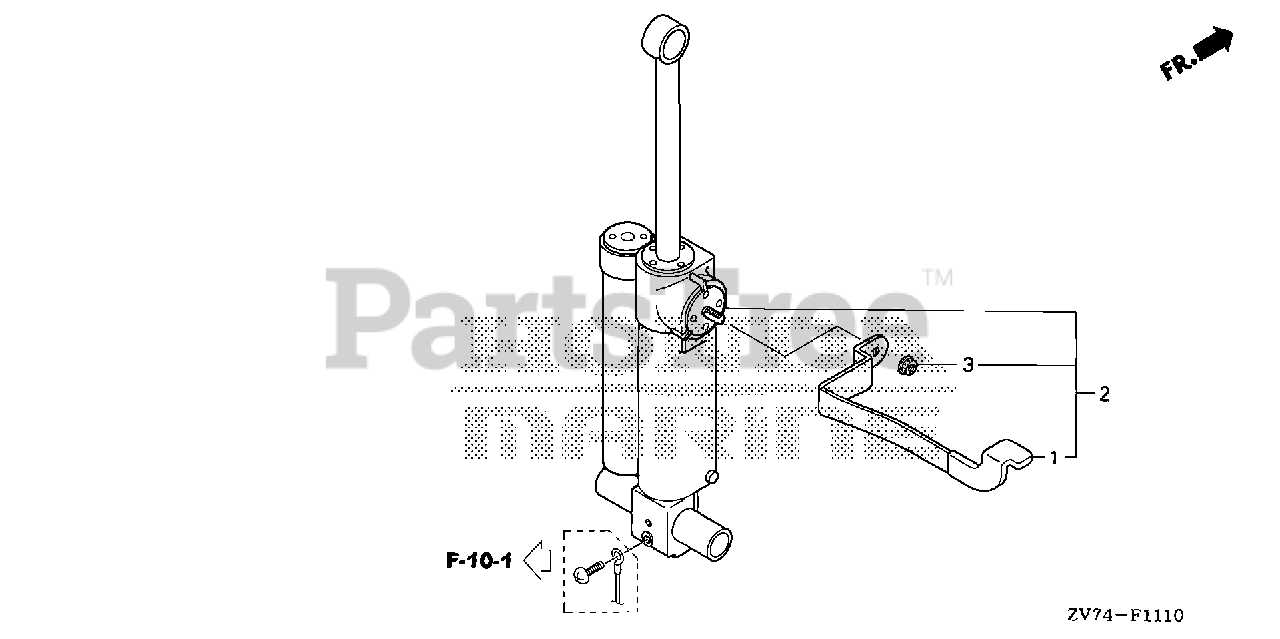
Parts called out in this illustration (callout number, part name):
1	LEVER, TILT
2	SHOCK ABSORBER ASSY., GAS
3	NUT, SELF-LOCK (6MM)
